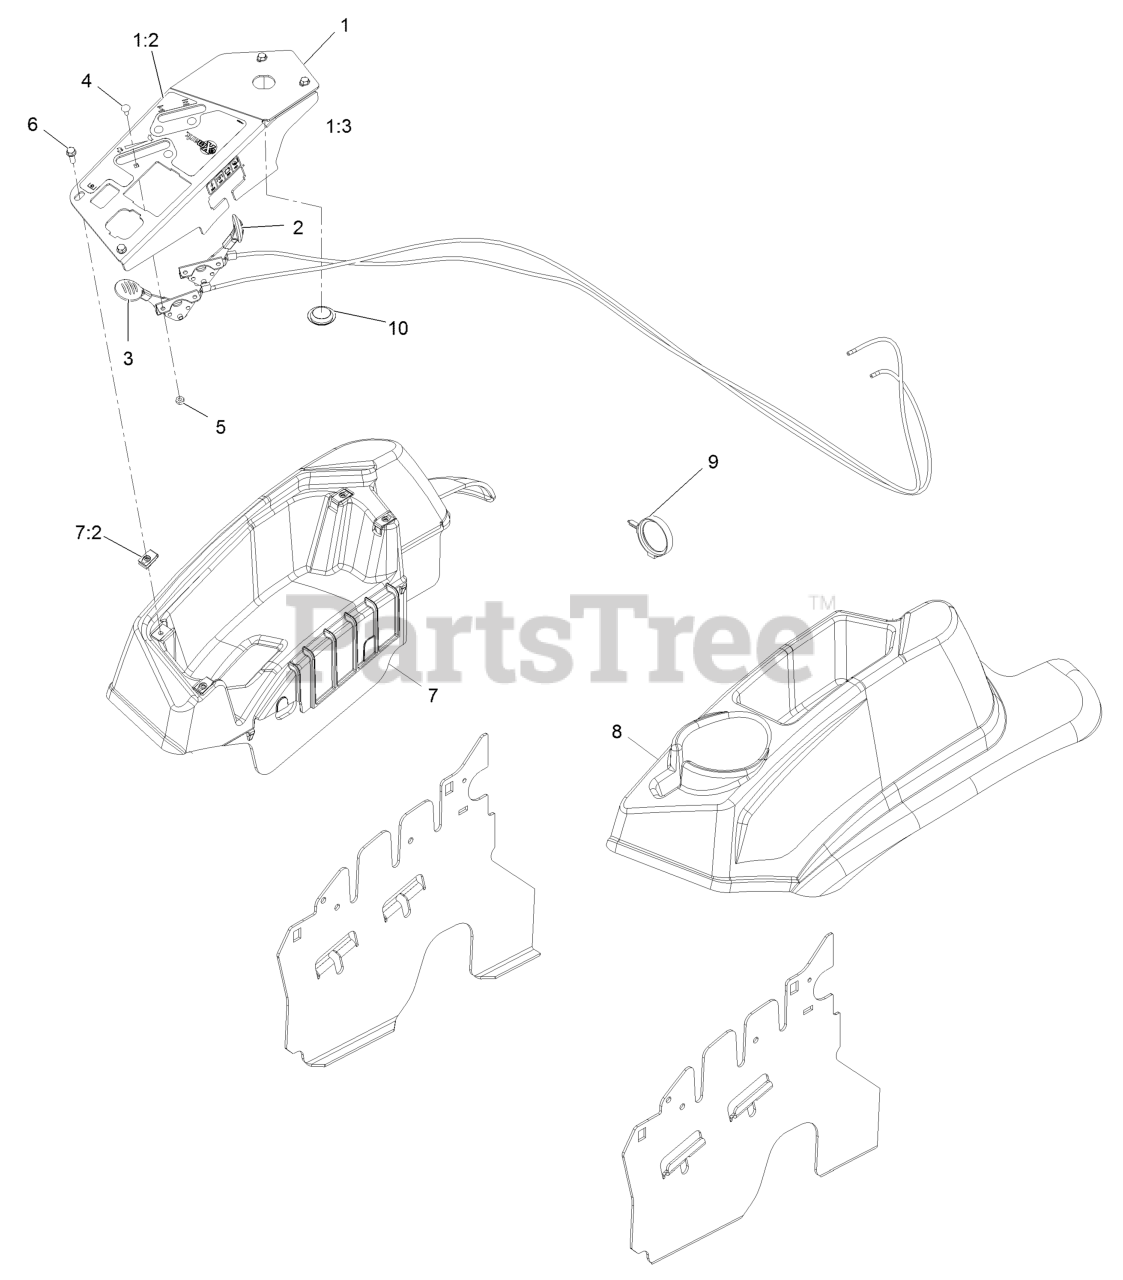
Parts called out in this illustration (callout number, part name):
1	ASM,CONSOLE PANEL W/DECAL
1:2	DECAL-CONTROL PANEL NON-E
1:3	DECAL-FUSES
2	ASM, CHOKE CABLE
3	ASM,THROTTLE CABLE
4	BOLT-CARR
5	NUT-LOCK, NI
6	SCREW-HWH
7	CONSOLE,RH AS ASM
7:2	Nut-Retainer-Panel 1/4-20
8	CONSOLE, LH AS
9	CLAMP-HARNESS
10	PLUG-PLASTIC
